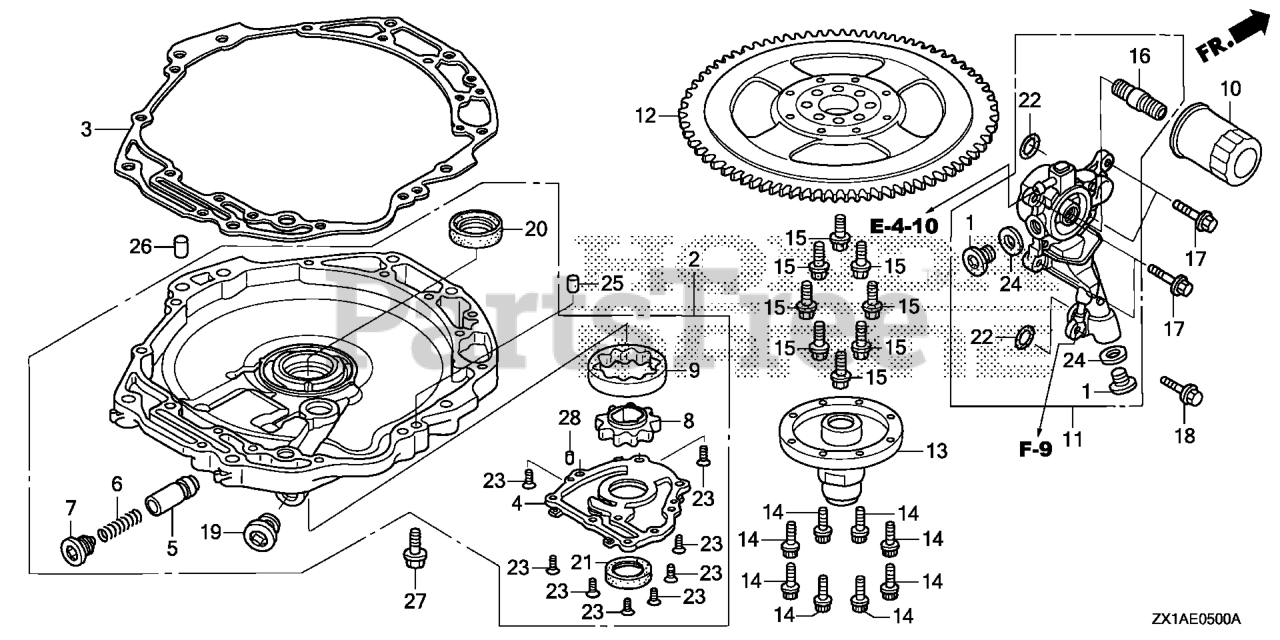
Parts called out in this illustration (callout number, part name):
1	BOLT, SEALING (20MM)
2	PUMP ASSY., OIL *NH8* (DARK GRAY)
2	PUMP, OIL *NH8*
3	GASKET, OIL PUMP BODY
4	COVER, OIL PUMP
5	VALVE, RELIEF
6	SPRING, RELIEF VALVE
7	BOLT, SEALING (18MM)
8	ROTOR, OIL PUMP (INNER)
9	ROTOR, OIL PUMP (OUTER)
10	FILTER, OIL (FILTECH TOYO ROKI) (SOLD IN MULTIPLES OF 30)
10	FILTER, OIL
11	FLANGE COMP *NH8*
12	FLYWHEEL *TBLACK* (BLACK)
13	BOSS, FLYWHEEL
14	BOLT, SPECIAL (8MM)
15	BOLT, FLANGE (12MM)
16	HOLDER, OIL FILTER
17	BOLT, FLANGE (6X25)
18	BOLT, FLANGE (6X20)
19	BOLT, SEALING (22MM)
20	OIL SEAL (46X60X9)
21	OIL SEAL (31X46X7) (NOK)
22	O-RING (22.5X2.4)
23	SCREW, FLAT (6X16) (YAMADA)
24	WASHER, DRAIN PLUG (20MM)
25	PIN A, DOWEL (10X16)
26	PIN A, DOWEL (14X20)
27	BOLT, FLANGE (8X32)
28	ROLLER (5X8)
